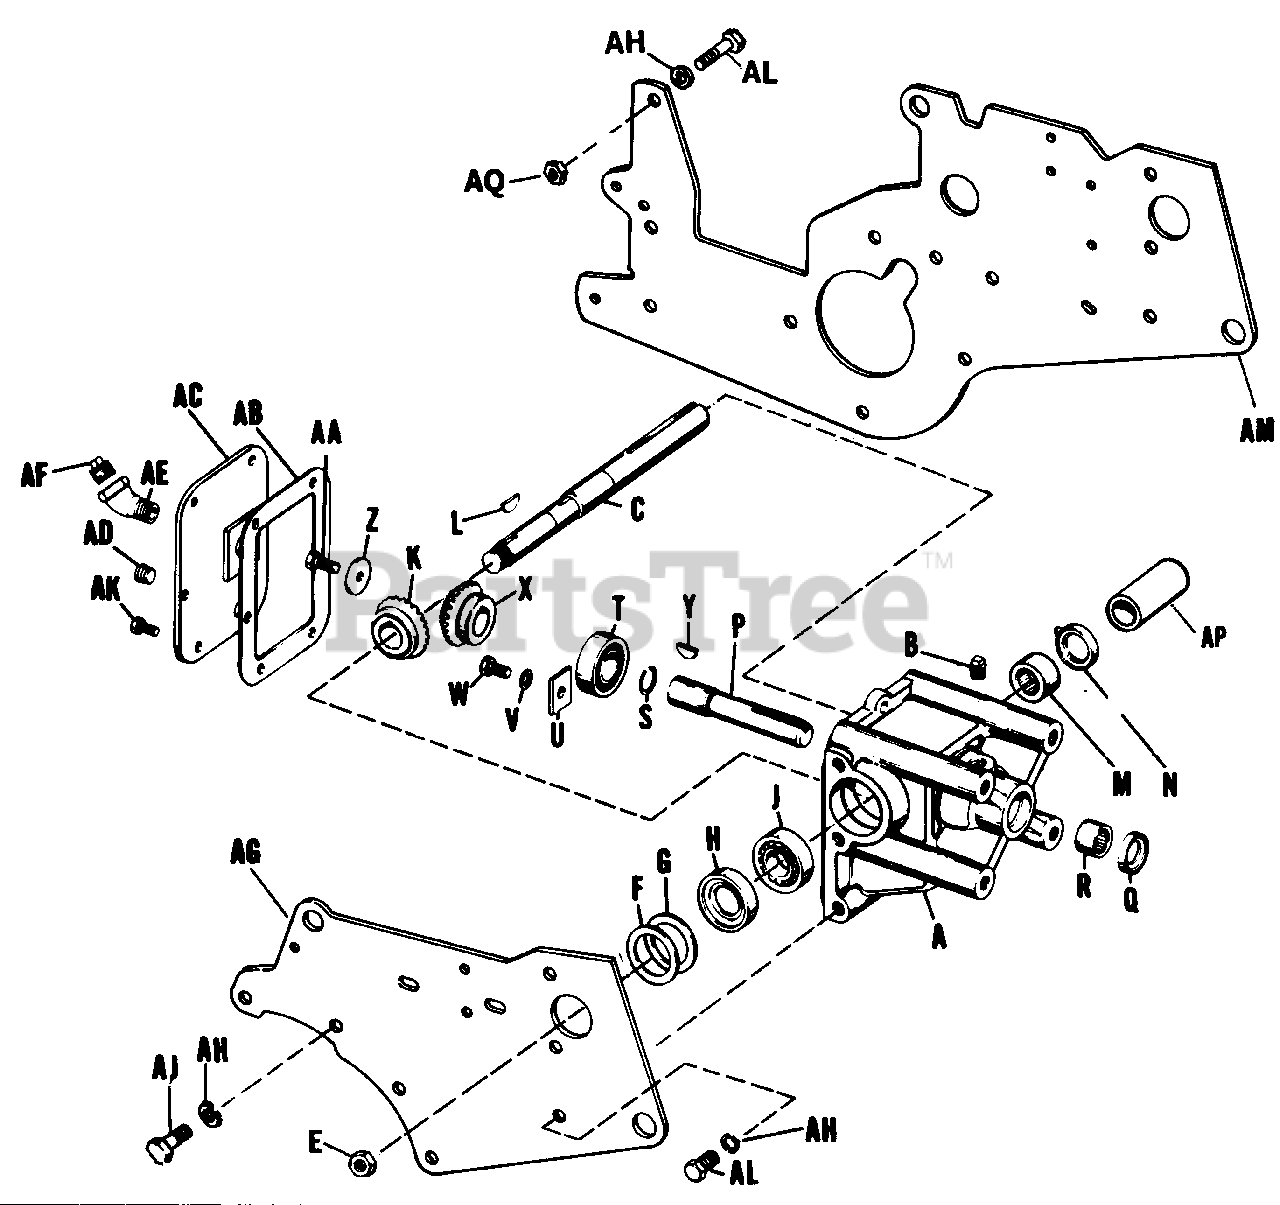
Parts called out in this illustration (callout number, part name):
A	Bevel Gear Housing, W/Bearings
B	Pipe Plug
C	Drive Shaft
E	Hex Jam Nut
F	Shim (As Required)
H	Oil Seal
J	Ball Bearing
K	Bevel Driven Gear
M	Needle Bearing
P	Driven Shaft
R	Needle Bearing
S	Retaining Ring
T	Ball Bearing
U	Bearing Clamp Plate
V	Lock Washer. 5/16"
W	Hex Capscrew, 5/16"-18 x 5/8" lg.
X	Bevel Driven Gear
AA	Hex Capscrew, 5/16"-18 x 3/4" lg.
AC	Housing Cover Assembly
AD	Pipe Plug
AE	Street Elbow
AF	Pipe Plug
AG	R.H. Side Plate
AH	Lock Washer, 7/16"
AJ	Hex Cap Screw, 7/16"-14 x 1" lg.
AK	Hex Cap Screw, 1/4"-20 x 5/8" lg.
AL	Hex Capscrew, 7/16"-14 x 1-1/4" lg.
AM	L.H. Side Plate
AQ	Full Hex Nut, 7/16"-14
